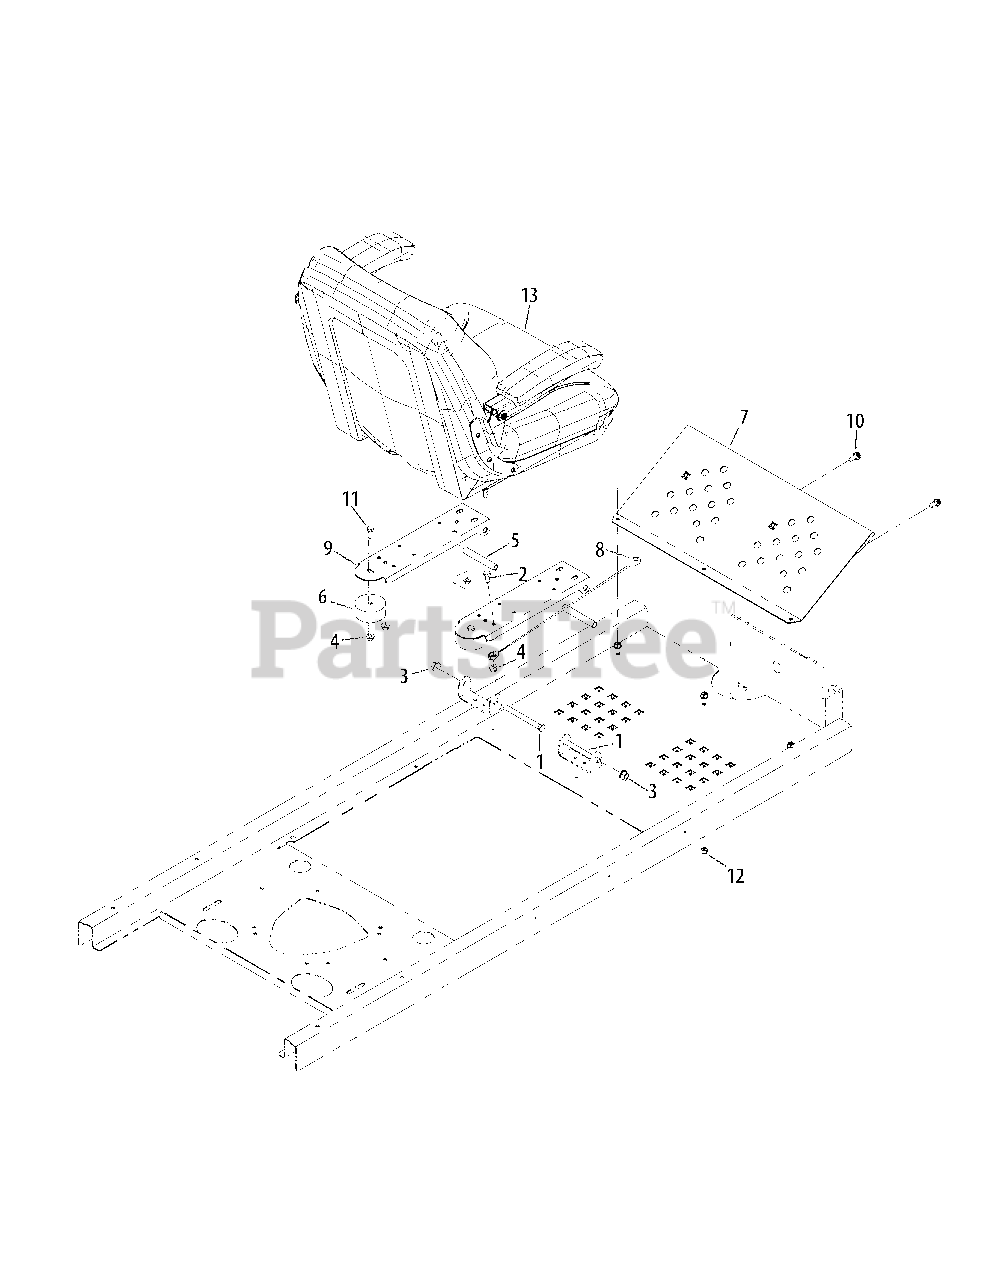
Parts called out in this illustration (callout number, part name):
1	Hex Cap Screw, 3/8-16 x 4.00
2	Hex Cap Screw, 5/16-18 x 3/4
3	Flange Lock Nut, 3/8-16
4	Flange Lock Nut, 5/16-18
5	Spacer, .370 ID x .500 x 3.45
6	Bumper, 2.50 x 1.13
7	Foot Rest Bracket
8	Lift Cable
9	Seat Mounting Bracket
10	Self Tapping Screw 5/16-18 x .750
11	Hex Cap Screw, 5/16-18 x .75
12	Nylock Nut, 5/16-18
13	Seat
